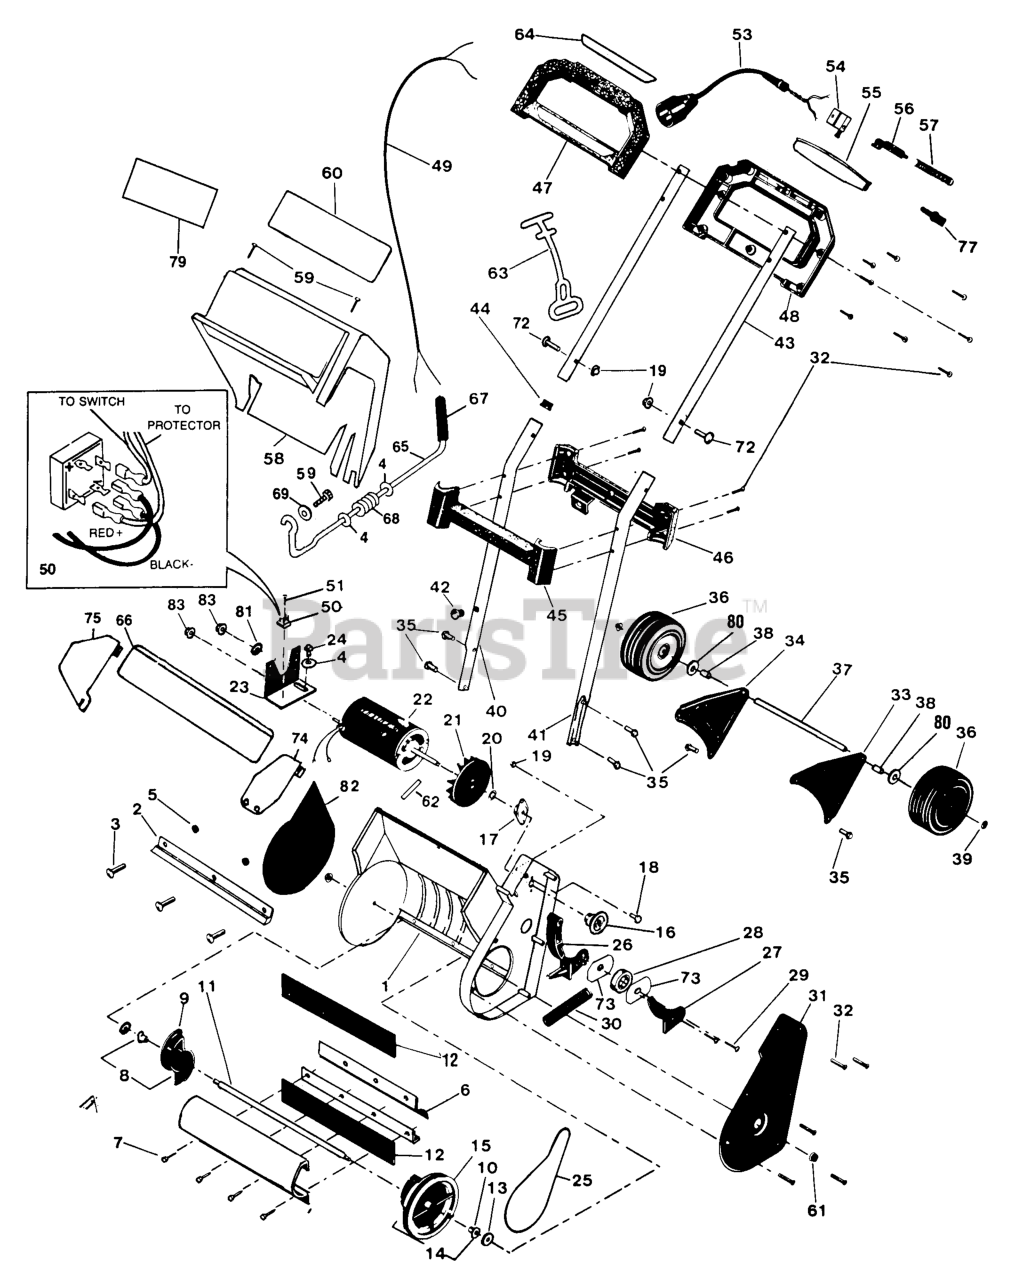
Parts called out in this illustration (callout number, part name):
1	HOUSING-SCOOP
2	BLADE, SCRAPER
3	BOLT, 1/4-20X .63 CARR
4	WASHER, FLAT .28X .63X.065
5	NUT, 1/4-20 WDFLWHIZ-LK
6	SEGMENT-DRUM
7	SCREW 10-24-3/4
9	CAP-DRUM END
10	BEARING-BRONZE
11	SHAFT-PADDLE
12	PADDLE-AUGER
13	WASHER, FLAT .328X .75
15	PULLEY-DRIVEN
16	PULLEY-DRIVE
17	BEARING, SELF ALIGN
18	SCREW, 1/4-20X .50
19	NUT, 1/4-20 HEXKEPS
20	RING, RET E.30X.04TRU5133-37
21	FAN,MOTOR
22	MOTOR,120V
23	BRKT, MOTOR MT.
24	SCREW, 1/4-14X .75
25	BELT-DRIVE
26	ARM-IDLER
27	RETAINER IDLER BRNG
28	BEARING - BALL
29	SCREW, #8 X.63 POLY
30	SPRING IDLER
31	COVER-DRIVE HSNG LH
32	SCREW, #8 X 3/4 POLY
33	BRKT, WHEEL LH
34	BRKT, WHEEL RH
35	SCREW, 1/4-20X .63 WAHHTAP
36	WHEEL, 15" SNOW SHOVEL
37	AXLE WHEEL
38	SPACE R-WHL,.328IDX.06X9/16L
39	NUT, PUSH ON CAP .312 OD
40	HANDLE, LOWER RH
41	HANDLE, LOWER LH
42	BUSHING
43	HANDLE, UPPER
44	PROTECTOR, HARNESS
45	HARNESS, PROTECTOR
46	SET,HANDLE.ASSIST
46-1	ORDER SET
46-2	ORDER SET
47	SET,HANDLE.GRIP
47-1	ORDER SET
47-2	ORDER SET
49	WIRE HARNESS
50	RECTIFIER, FULL WAVE
51	SCREW, #6 X .50
53	CONNECTIN LEAD
54	SWITCH, TRM 2516LOV
55	BAR-SWITCH
56	LEVER-SWITCH
57	SPRING - SWITCH
58	COVER-MOTOR
59	SCREW, 10-16X .63
61	NUT, 5/16-18 WDFLLK
62	PIN, GROOVED.125 DIAX.63LG
63	STRAIN RELIEF, CORD
65	ROD-DISCHARGE
66	SLIDER-VANE
67	GRIP, HAND VINYL
68	SPRING,ACTUATOR ROD NEW-15
69	WASHER, FLAT .750X .22X.070
72	BOLT, 1/4-20X1.25
73	RETAINER-BELT
74	OUTER DEFLECTOR
75	INNER DEFLECTOR
77	KEY, HI-PRO
80	WASHER, FLAT
81	GROMMETT.5 X .81 #GRO 1/2UL
82	COVER-HSNG RH
83	NUT, #10-32 HNYLLK
